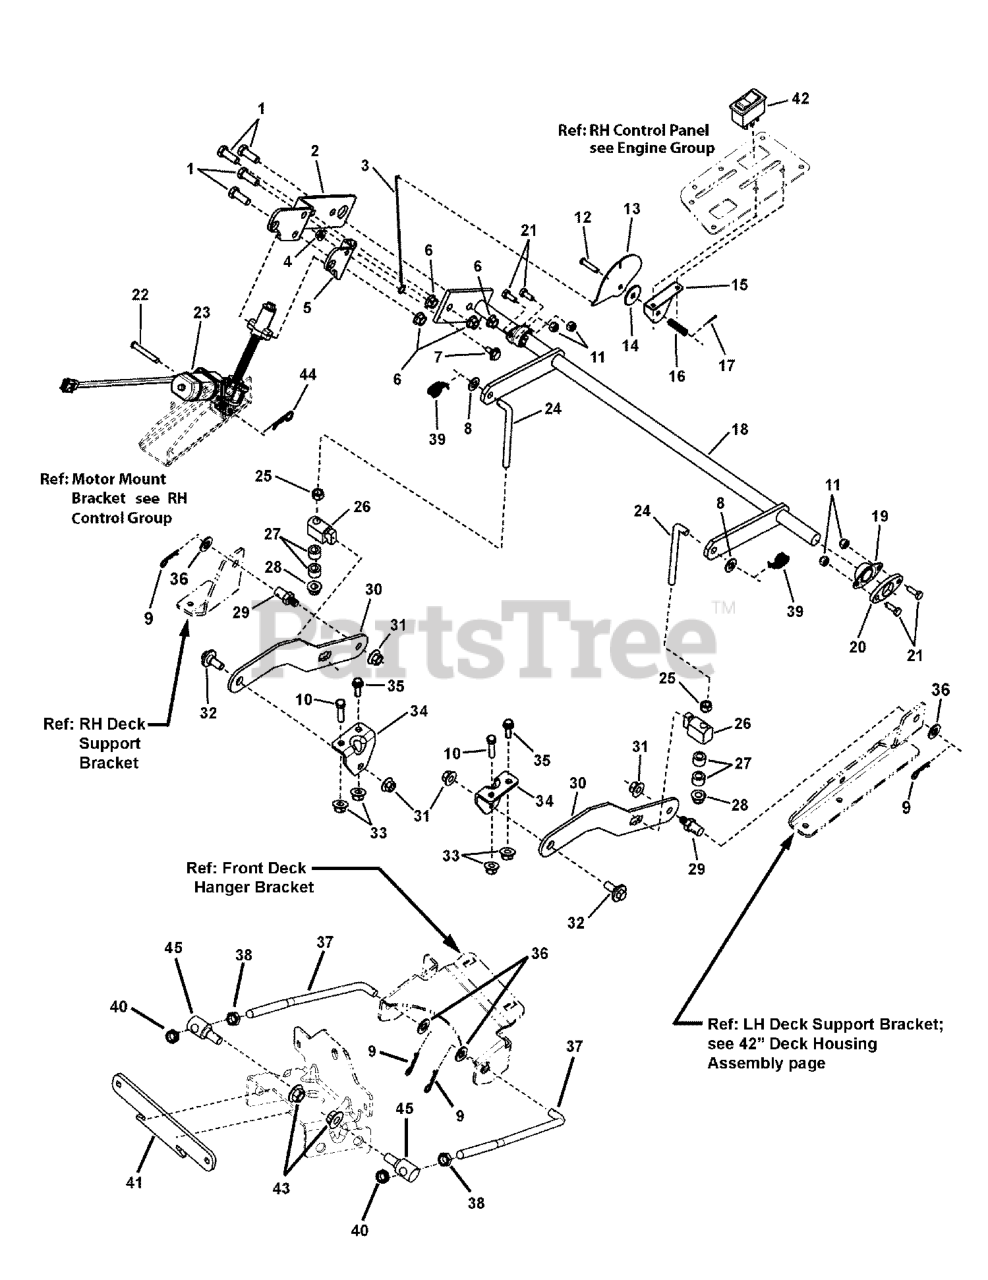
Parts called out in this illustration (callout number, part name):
1	SCREW, 3/8-16 x 1" Hex Head Cap, GR 5, YZ
2	BRACKET, Lift, Deck, Primary
3	ROD, Indicator, Height-Of-Cut
4	NUT, 1/4-20 Hex Flange Lock, GR 5, YZ
5	BRACKET, Lift, Deck, Secondary
6	NUT, 3/8-16 Hex Flange lock, YZ
7	SHOULDER BOLT, 1/4-20 x 3/8"
8	WASHER, 3/8" Flat (SAE)
9	HAIR PIN, 3/32 x 1-1/2" YZ
10	SCREW, 1/4-20 x 5/8" Hex Head Cap, GR 5
11	NUT, 1/4-20 Hex Nyloc, YZ
12	CLEVIS PIN, .25 x 1.09
13	LEVER, Indicator, Height-Of-Cut
14	WASHER, 5/16" Nylon
15	BRACKET, Indicator, Height-Of-Cut
16	SPRING, Compression
17	COTTER PIN, .06 x 1/2" YZ
18	WELDMENT, Deck Lift, 38/42
19	BEARING, Flange, .75 ID PM
20	SPACER, Bearing, .25"
21	SCREW, 1/4-20 x 3/4" Hex Head Cap, GR 5 YZ
22	SHEAR PIN, .248 ID x 1-3/4" Long
23	MOTOR, Actuator, Lift, Deck
24	ROD, Mower Lift (3/8-16 thread) Yellow
25	NUT, 3/8-16 Hex, Black
26	TRUNNION, Powdered Metal, Yellow, Regent
27	SPACER, .385 ID x .6697 OD x .455 Long, PM Yellow
28	NUT, 3/8-16 Hex Flange Esna, Black
29	PIN, 3/8-16 Threaded Shoulder
30	BAR, Rear Lift
31	NUT, 3/8-16 Hex Flange Center Lock, Zinc Plated
32	SHOULDER BOLT, 3/8-16 x .94, BZ
33	NUT, 5/16-18 Flange Lock, YZ
34	BRACKET, Deck Hanger
35	BOLT, 5/16-18 x 5/8" Hex Flange lock, GR 5, YZ
36	WASHER, 1/2" Flat (0.51 ID x 1.00 OD x .10 Thick) Black
37	ROD, Front Bail (1/2-13 thread) MWR
38	NUT, Hex Jam, 1/2-13
39	TRUNNION, Unthreaded
40	NUT, Hex Lock, 1/2-13
41	NUT, Hex Flange, Two-Way Lock, 1/2-13
42	SUPPORT, Hanger
43	SWITCH, Rocker Electric Height-Of-Cut
44	CAPSCREW, Hex Head, 5/16-18 x 1
45	COTTER PIN, 3/8" Self Lock
